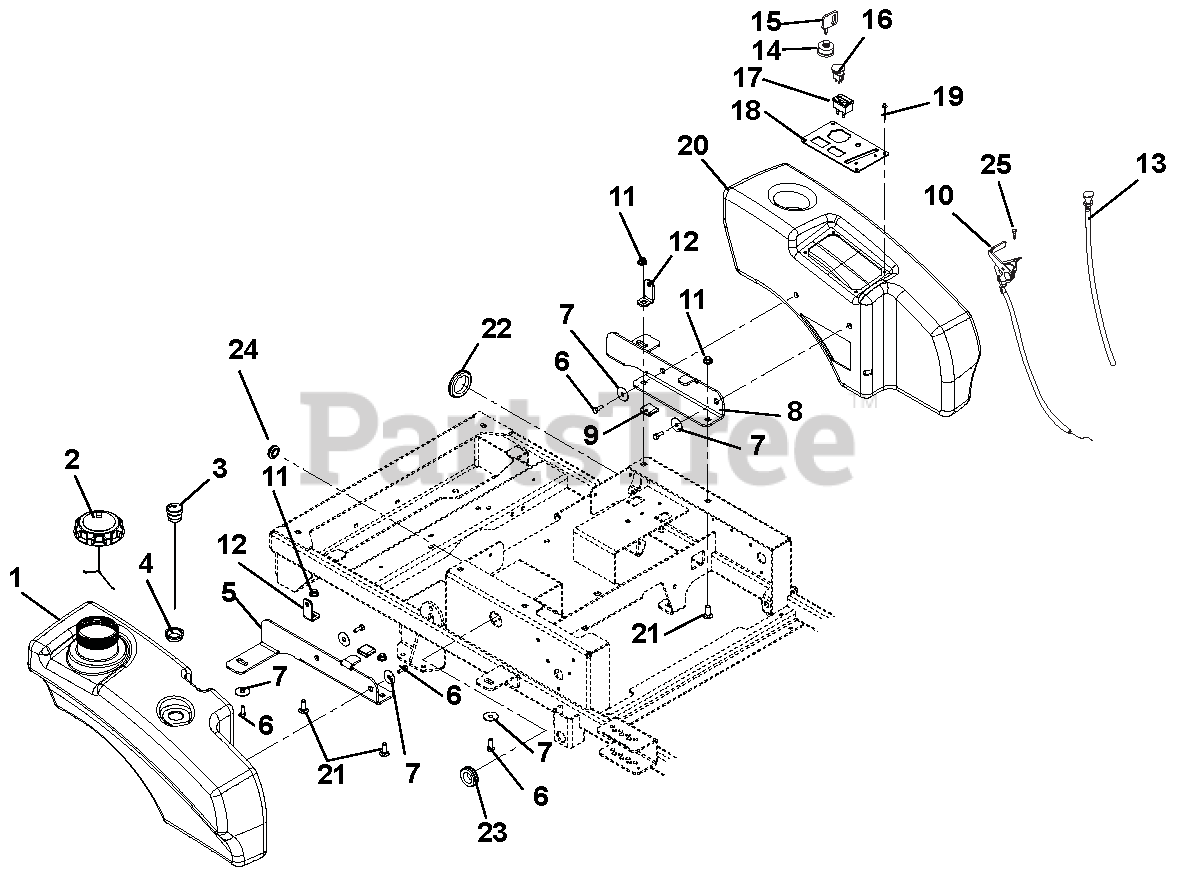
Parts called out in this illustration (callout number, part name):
1	KIT, XL TANK REPLACEMENT
2	CAP, FUEL
3	GAUGE, REMOTE FUEL 10.0"
4	GROMMET, FUEL GAGE
5	BRKT, RH REAR TANK MOUNT
6	BLT-SERHFWH .312-18X.50 YWZC
7	WSHR-FL-STL .347X1.254X.048YWZ
8	BRKT, LH REAR TANK MOUNT
9	GRIP, RUBBER (1.0X1.0X.187)BLK
10	CABLE-THROTTLE
11	@NUT-LK-NYL-FLG .38-16 YWZC
12	BRKT, HOOD PIVOT
13	CABLE, CHOKE
14	KEY SWITCH
15	KEY -W/CAP
16	SWITCH, CLUTCH
17	HOUR METER - DIGITAL
18	CONTROL PANEL
19	RIVET, PLASTIC .195 DIA.
20	FENDER, XL
21	@BLT-RDHDSQNK .38-16X1.00 G5YZ
22	GROMMET 1.70ID X 2.0OD
23	GROMMET 1.0ID X 1.38 OD
24	GROMMET,RUBBER 5/8 ID/1.13 OD
25	@SCR-TAP 10-24X.50 HWH TR YWZC
